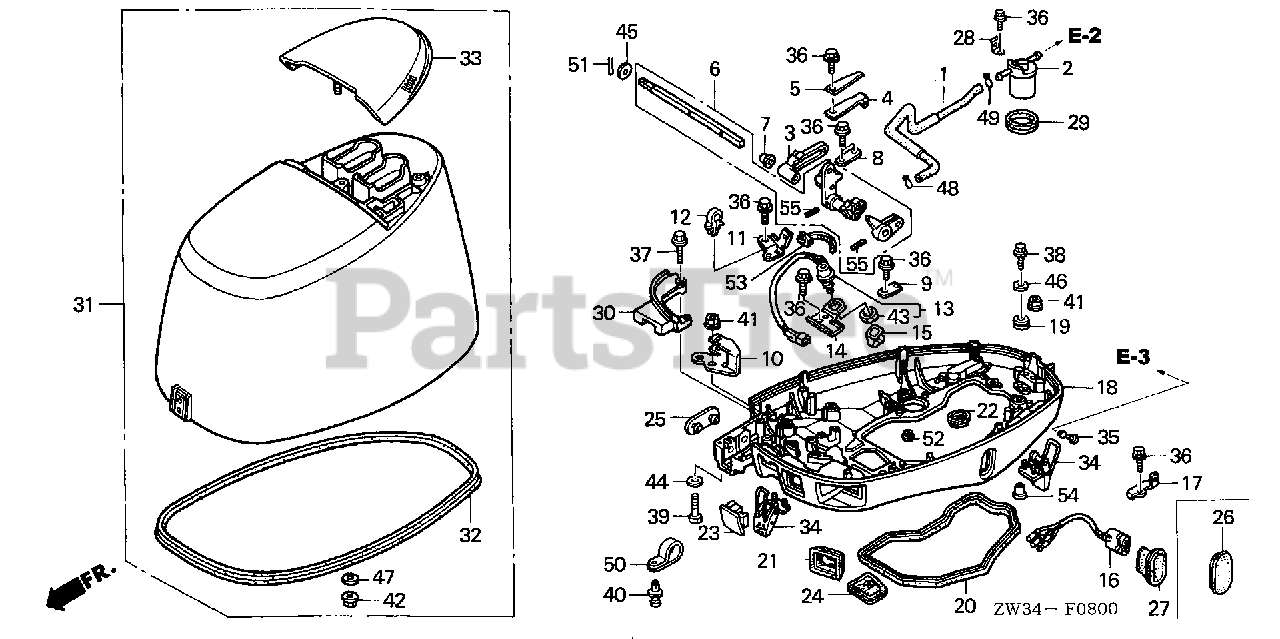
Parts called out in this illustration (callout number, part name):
1	TUBE, FUEL
2	STRAINER, FUEL (TOYO ROKI)
3	ARM, THROTTLE
4	SPRING, CLICK
5	SPRING, CLICK ASSIST
6	SHAFT, SHIFT
7	BUSH, SHAFT
8	PLATE, SHIFT
9	PLATE, SHIFT SHAFT
10	BRACKET, CONNECTOR
11	BRACKET, CABLE CLIP (S)
12	CLAMP, WIRE
13	SWITCH ASSY., NEUTRAL
14	BRACKET, NEUTRAL SWITCH
15	PLATE, NEUTRAL SWITCH
16	SWITCH ASSY., POWER TILT
17	STAY, POWER TILT SWITCH
18	CASE, ENGINE (LOWER) *NH282MU* (OYSTER SILVER METALLIC-U)
19	GROMMET, CASE (LOWER)
20	SEAL, CASE (LOWER)
21	GROMMET, CASE (LOWER) (B)
22	GROMMET, CASE (LOWER) (C)
23	GROMMET, CASE (LOWER) (D)
24	GROMMET, CASE (LOWER) (E)
25	GROMMET, CASE (LOWER)
27	GROMMET, CASE (LOWER) (G)
28	RETAINER, FUEL STRAINER
29	GROMMET, FUEL STRAINER
30	CASE, SEPARATE *NH282MU* (OYSTER SILVER METALLIC-U)
31	COVER, ENGINE *NH282MU* (OYSTER SILVER METALLIC-U)
32	SEAL, ENGINE COVER
33	HANDLE, TILT *NH282MU* (OYSTER SILVER METALLIC-U)
34	LEVER, FASTENER
35	GROMMET, WATER CHECK
36	BOLT, FLANGE (6X12) (CT200)
37	BOLT, FLANGE (6X28) (CT200)
38	BOLT, FLANGE (6X28)
39	BOLT, HEX. (6X40)
40	SCREW, RIVET (5X10)
41	NUT, SELF-LOCK (6MM)
42	NUT, U (6MM) (FUSE RASHI)
43	NUT, HEX. (20MM)
44	WASHER, PLAIN (6MM)
45	WASHER (7.5MM)
46	WASHER, PLAIN (6MM)
47	WASHER (6MM)
48	CLIP, TUBE (B12)
49	CLIP, TUBE (B12)
50	CLIP (14MM)
51	PIN, SPLIT (2.0)
52	PLUG, CHANGE REINFORCEMENT
53	CLIP, HARNESS BAND (145MM) (BLACK)
54	COLLAR, MODULE IGNITION CONTROL CASE (CDI)
55	PIN, SPRING (3X20)
